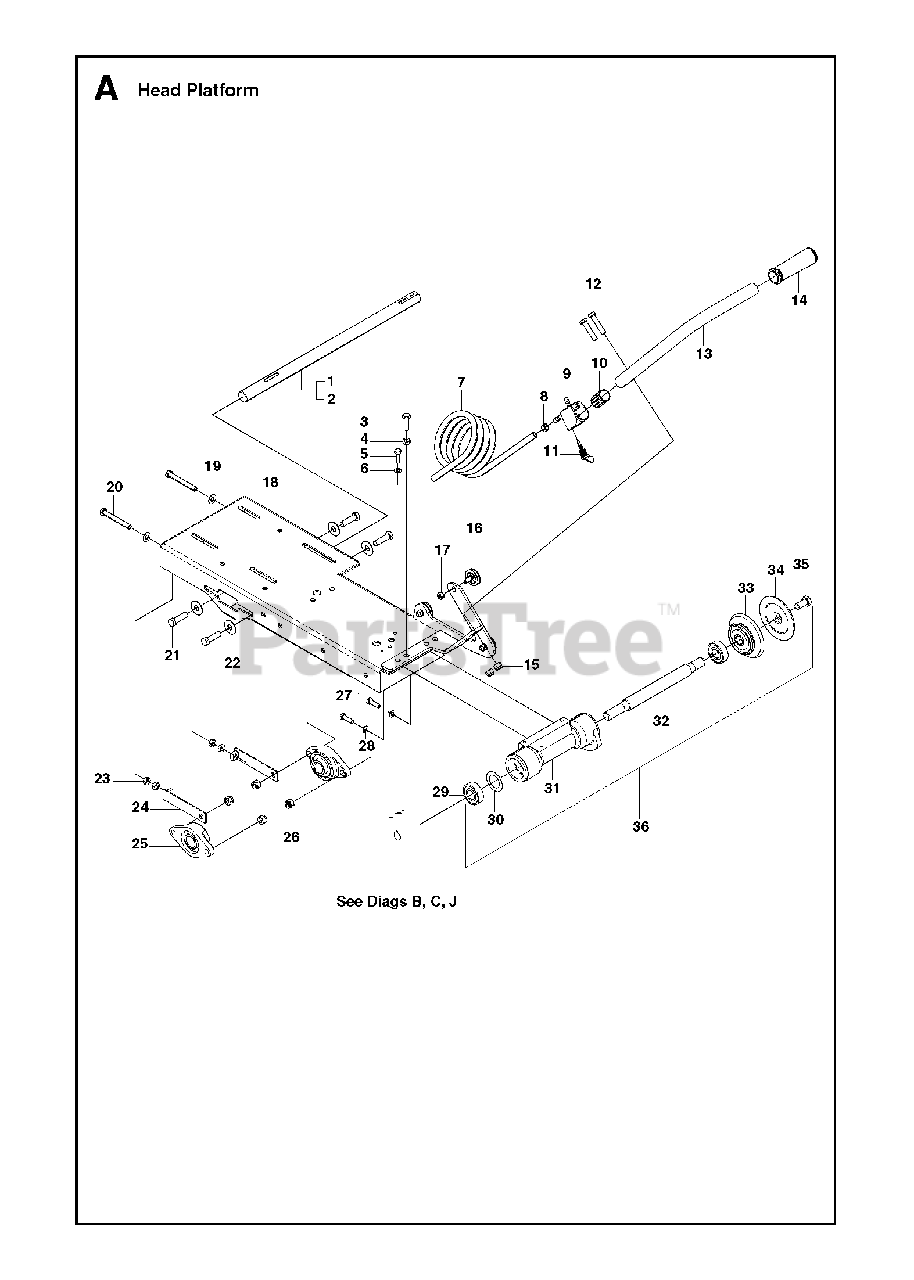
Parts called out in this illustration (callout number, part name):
1	SHAFTMS510 Electrical
6	WASHER
15	NUT
16	FS700/2/900/2 WHEEL SUR/BEARIN
19	WASHER
28	WASHER
